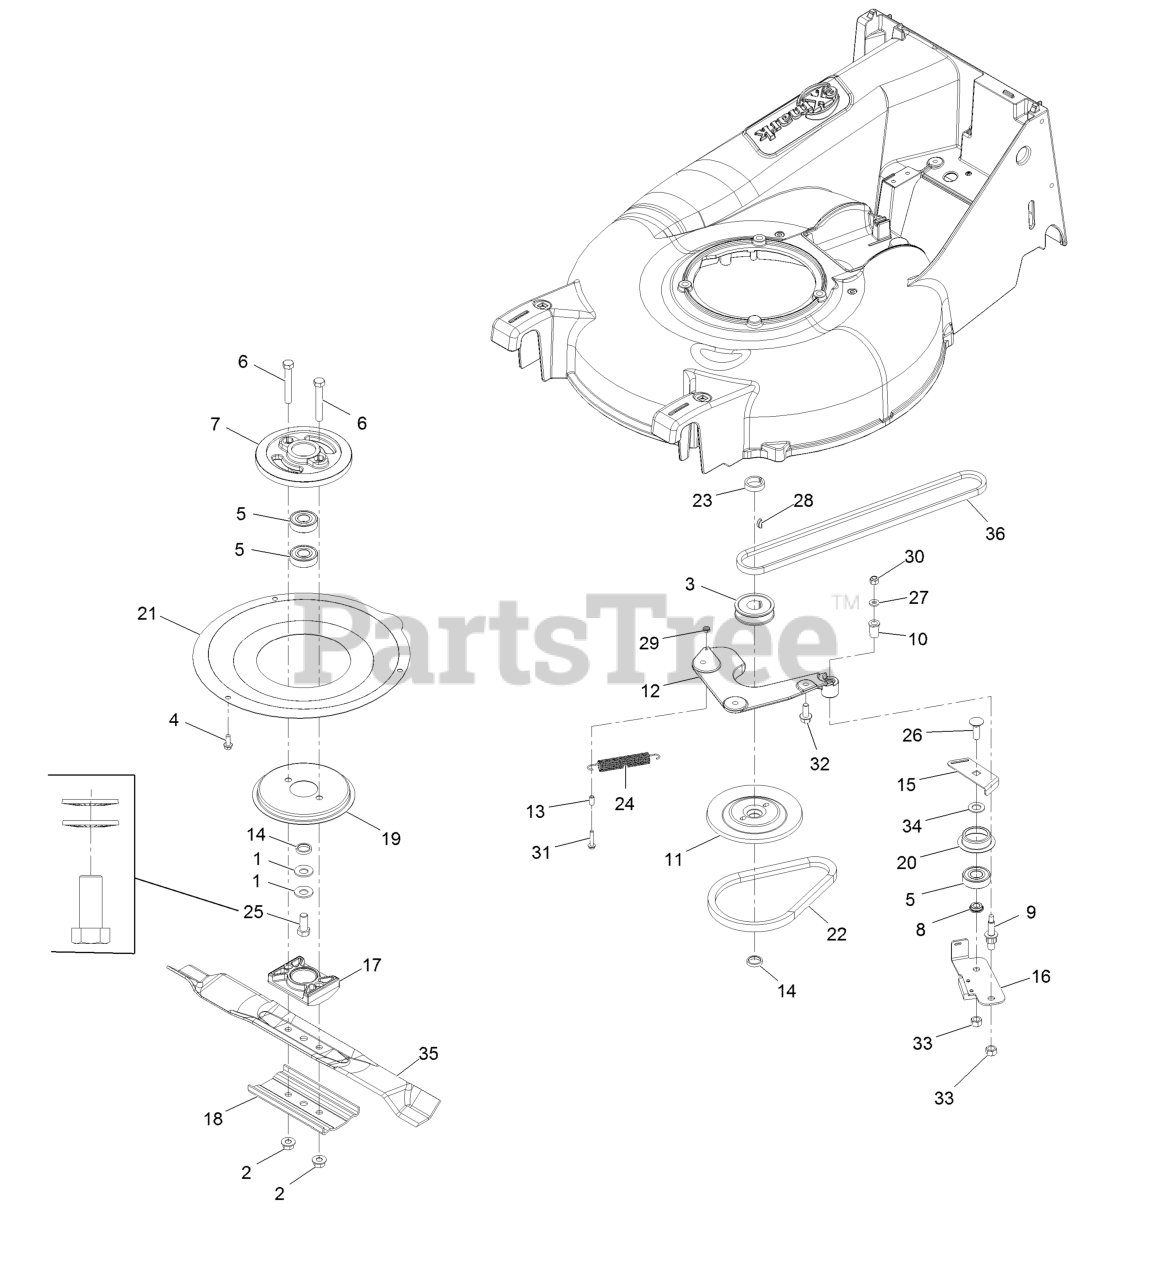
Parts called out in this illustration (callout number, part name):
1	Washer-Spring Disc 7/16
2	Nut-Flange, Lock
3	Pulley-Driver
4	Screw-HWH 1/4-20 X .62
5	Bearing-Ball
6	Screw-HH 3/8-24 X 2 1/2
8	Spacer-Bearing
9	Bolt-Shoulder
10	Bushing
11	Pulley-Driver, Upper
12	Plate-Mounting, BBC
13	Spacer-BBC
14	Spacer-Plate, BBC
15	Plate-Guide
16	Plate-Brake
17	Support-Blade
18	Support-Blade
19	Disc
20	Retainer-Belt
21	Cover-BBC
22	Belt
23	Spacer-Pulley
24	Spring-Extension
25	Screw-HH 7/16-20 X 1
26	Bolt-Carriage 3/8-16 X 1 1/4
27	Washer-#12 Std
28	Key-Woodruff
29	Nut-Lock #10-32
30	Nut-Nyloc 1/4-20
31	Screw-HWH #10-32 X 1 Taptite
32	Screw-HH M8-1.25 X 20Mm
33	Nut-Hex
34	Spacer
35	Blade - Medium Lift, 20.5
36	Belt,3L P21 Drive
